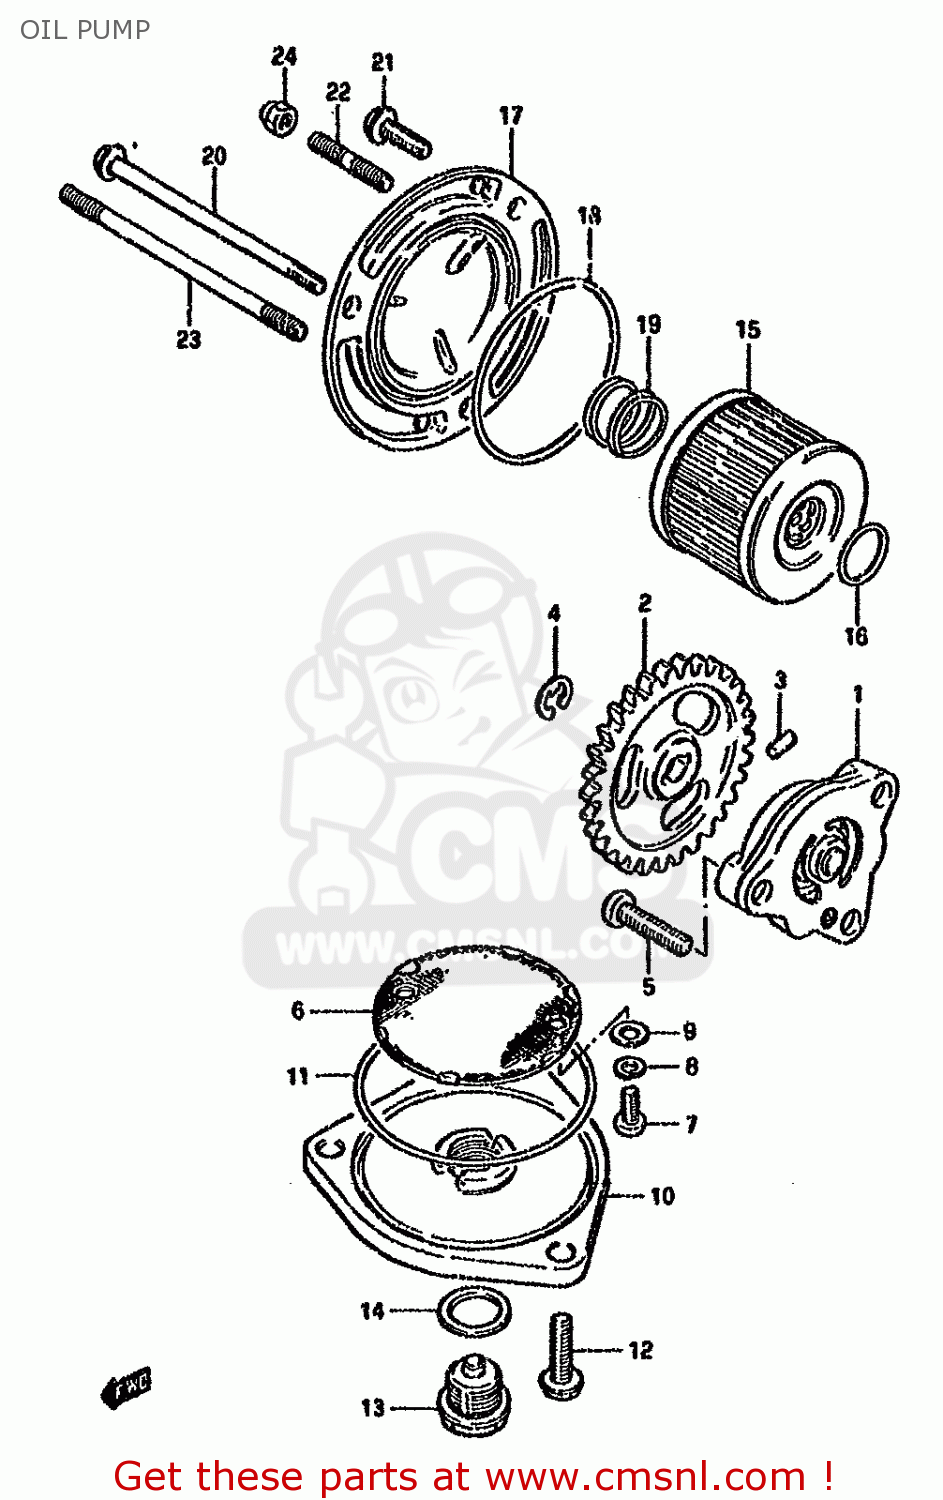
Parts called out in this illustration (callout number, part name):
1	PUMP ASSY,ENGINE OIL
2	GEAR,ENG OIL PUMP DRIVEN(NT:30
3	PIN(2.5X11.8)
4	E.RING
5	SCREW
6	STRAINER,ENGINE OIL
7	SCREW 5X12
8	LOCK WASHER
9	WASHER
10	CAP,OIL STRAINER
11	O RING(D:2.4,ID:60.5)
12	BOLT
13	PLUG
14	GASKET(13.8X18.8X4.8) (NAS)
15	FILTER ASSY,ENGINE OIL
16	O RING(D:1.9,ID:13)
17	CAP,OIL FILTER
18	O RING(D:2.4,ID:52.6)
19	SPRING
20	BOLT
21	BOLT
22	STUD 6X12
23	STUD BOLT, 6X8
24	NUT
